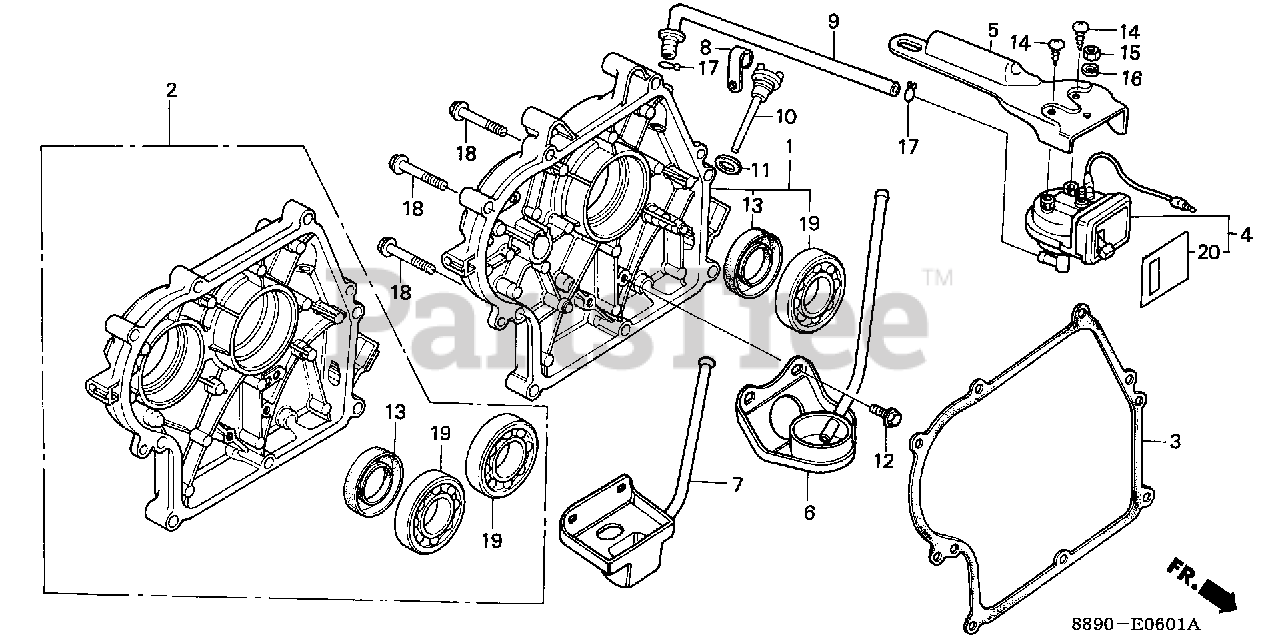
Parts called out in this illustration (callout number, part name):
1	COVER, CRANKCASE
3	GASKET, CASE COVER
4	SWITCH ASSY., OIL ALERT UNIT
5	BRACKET, OIL ALERT UNIT SWITCH
8	CLAMP, TUBE
9	TUBE, OIL ALERT
10	CAP, OIL FILLER (YELLOW)
11	GASKET, OIL FILLER CAP
12	BOLT, FLANGE (6X16)
13	OIL SEAL (30X46X8)
14	SCREW, TAPPING (5X10)
15	NUT, HEX. (5MM)
16	WASHER, SPRING (5MM)
17	CLIP, TUBE (C11)
18	BOLT, FLANGE (8X40)
19	BEARING, RADIAL BALL (6206)
